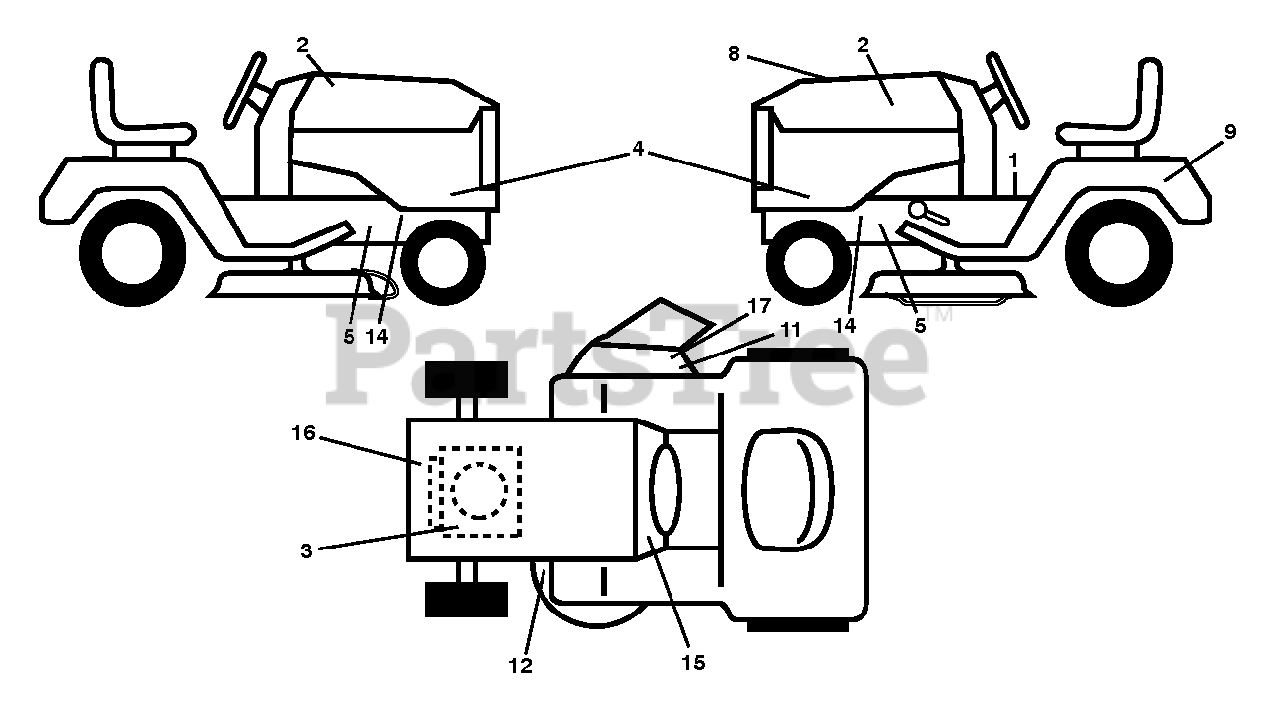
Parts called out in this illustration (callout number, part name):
1	DECAL TRACTOR SADDLE DECAL DEC
2	DECAL.BADGE.170MM.TEXTLOGO.
3	DECAL.ENGINE.WARNING
4	DECAL.SDPNL.HUSQLT.TS138
5	DECAL.CHASSIS.HOT.MUFFLER
8	DECAL.RPL.BSM31.INTK.TLW.38.GE
9	DECAL BTRY SYMBOLS
11	DECAL.DFLCTR.WARNNG.CTFNGR.SYM
12	DECAL.DECK.SCH.36,38,94.NONCR
14	DECAL.WARNING.SERVCE/FIRE
15	DECAL.SNOWFLAKE.MS498.HUSQ
16	DECAL.ENG.B&S.HS.500CC.382338
17	DECAL, DECK DEFLECTOR, WARNING
